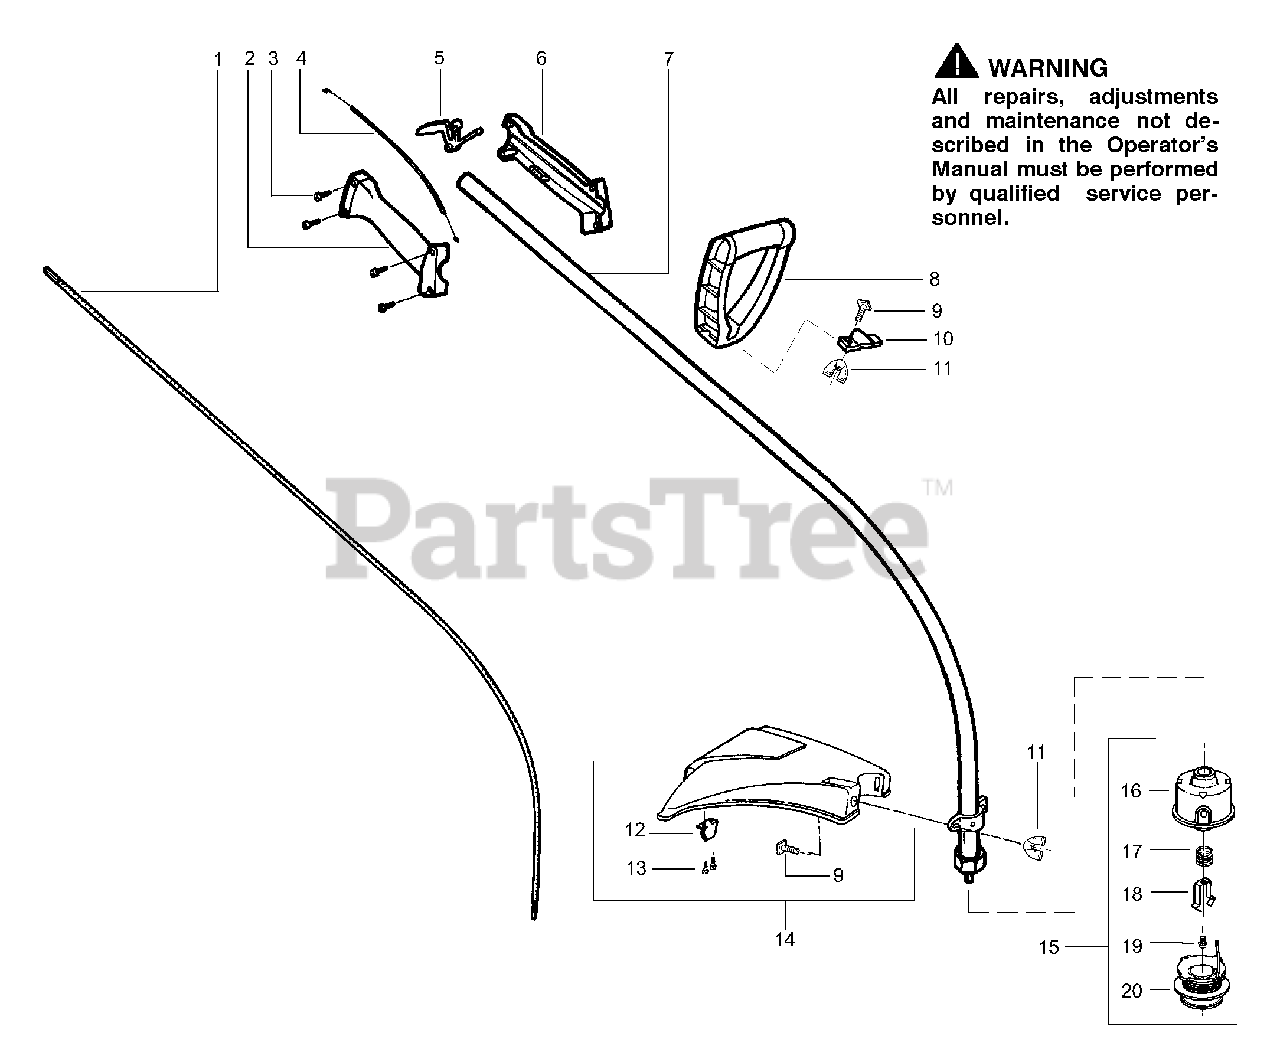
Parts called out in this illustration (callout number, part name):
1	Shaft Flex
2	Throttle Hsg. (Right)
3	Screw Throttle Hsg.
4	Assy Throttle Cable
6	Hsg. Throttle (Left)
7	Assy Drive Shaft Hsg.
8	Handle Assist
9	Bolt Handle/Shield
10	Clamp Handle
11	Wingnut Handle/Shield
12	Line Limiter
13	Screw Line Limiter
14	Kit Shield Ass'y.
15	Accy Cutting Head
16	Ass'y Hub
17	Spring Compression
18	Clip Retainer Head
19	Screw w/ Washer Head
20	Spool w/Line
